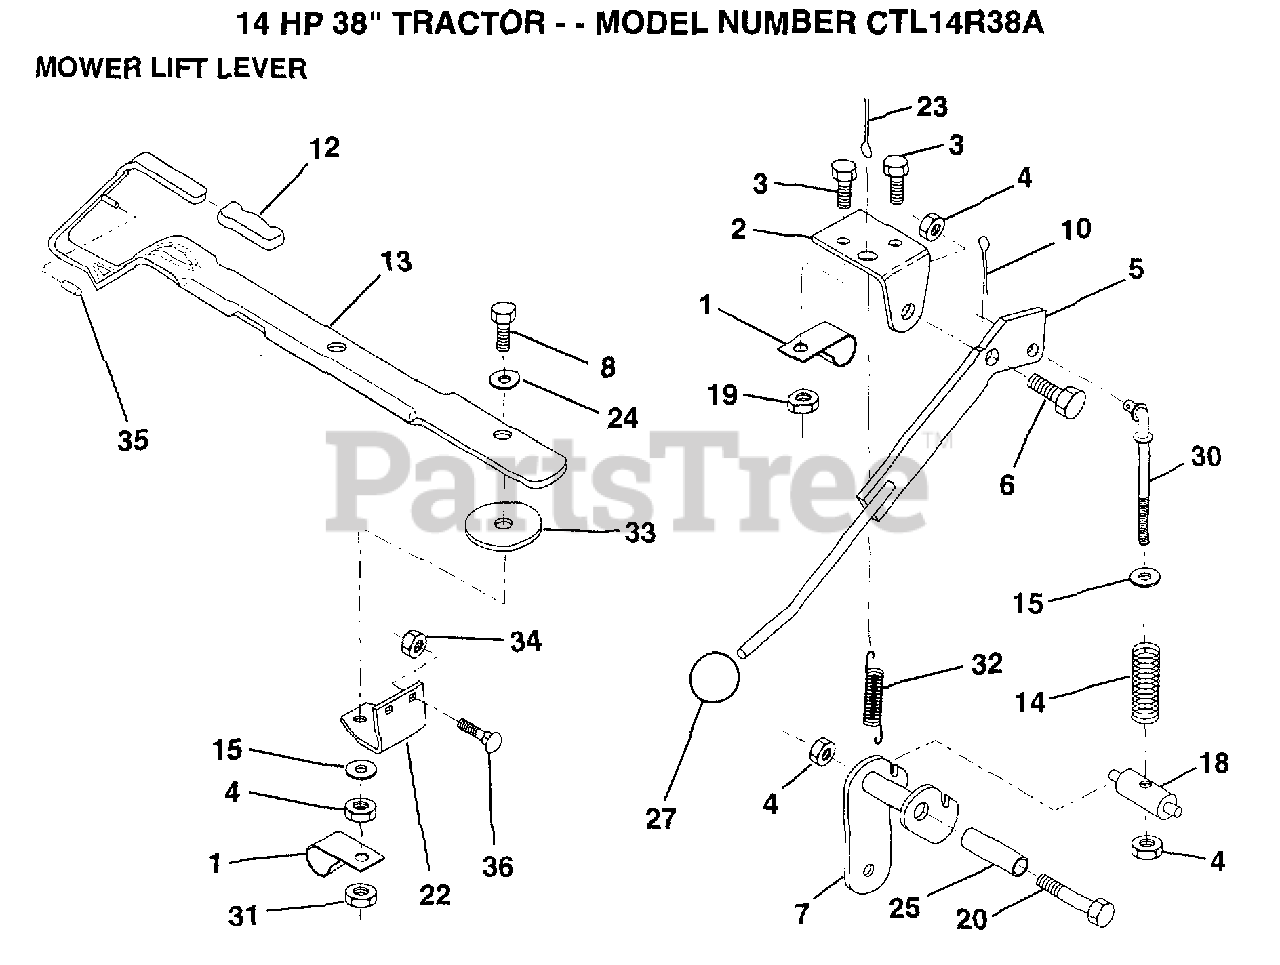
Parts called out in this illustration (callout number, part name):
1	"CLIP,INSULATOR"
2	BRKT CLUTCH
3	BOLT
4	NUT
5	CLUTCH LEVER AS
6	"BOLT, SHOULDER LT"
7	ARM.CLUTCH.ASM
8	BOLT
10	COTTER PIN
12	GRIP HANDLE
13	LEVER LIFT LR
14	COMP CLUTCH SPRNG
15	WASHER HYT
18	TRUNNION
20	BOLT
22	LIFT LEVER BRKT
24	WASHER
25	TUBE SPACER
27	KNOB
30	ROD TENSION CLUTC
31	LOCKNUT
32	SPRING EXT
33	WASHER
34	NUT
35	VINYL CAP RED
36	BOLT
